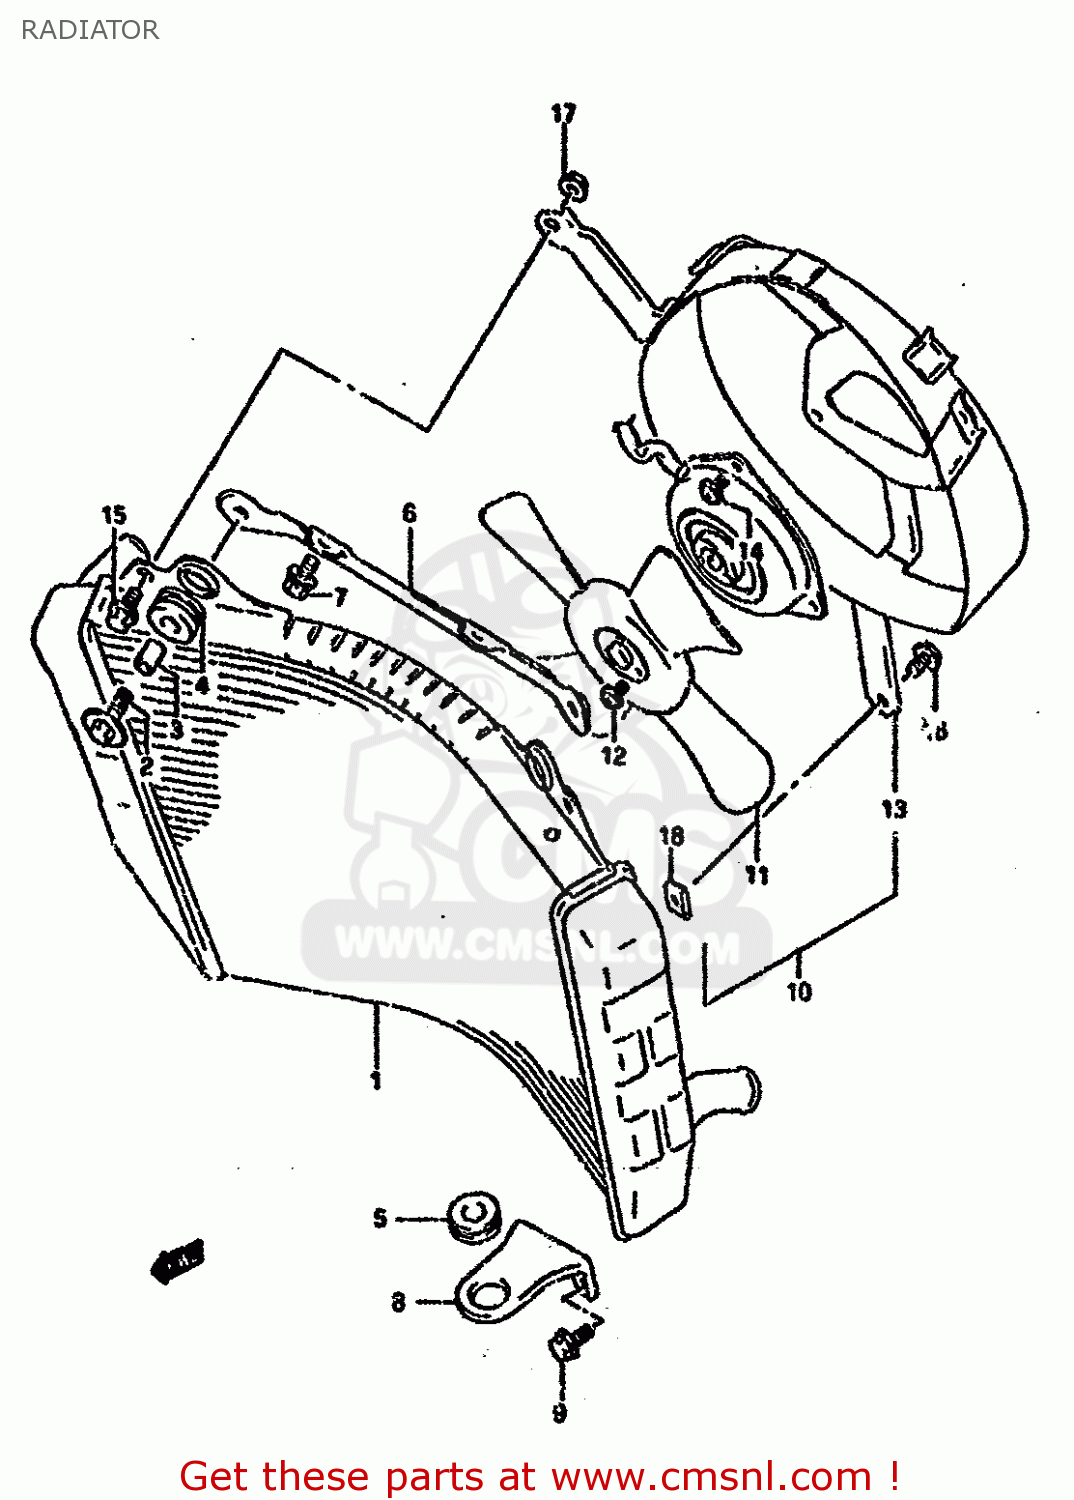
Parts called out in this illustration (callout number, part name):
1	RADIATOR ASSY,WATER
2	BOLT(6X25)
3	SPACER(6.5X10.5X12)
4	CUSHION,RADIATOR LWR
5	CUSHION
6	BRACKET COMP,RADIATOR
7	BOLT
8	BRACKET,RADIATOR,LOWER
9	BOLT
10	FAN ASSEMBLY,RADIATOR
11	FAN
12	SCREW 4X6
13	SHROUD
14	SCREW
15	BOLT
16	BOLT
17	NUT
18	NUT,RADIATOR COVER
